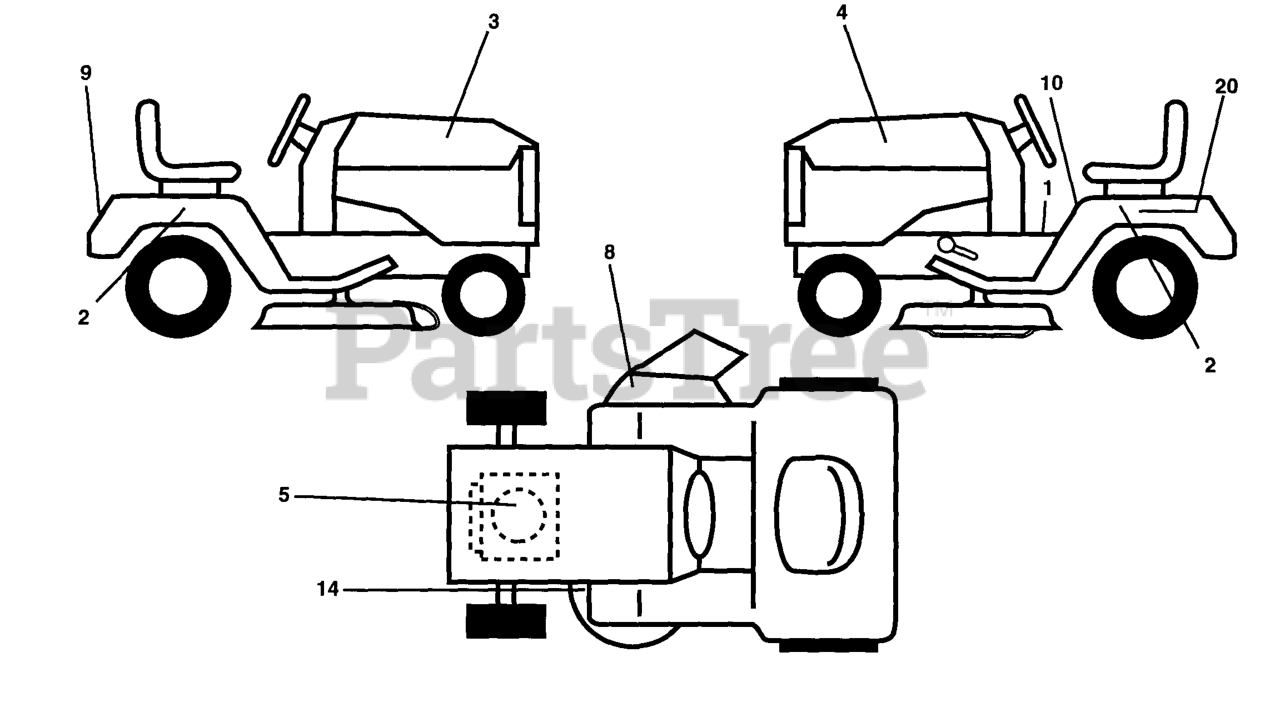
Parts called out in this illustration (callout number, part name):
3	DECAL HOOD LH
4	DECAL HOOD RH
5	DECAL HP ENGINE
8	DECAL WARNING (ENGLISH/FRENCH)
9	DECAL FENDER HUSQ
10	DECAL FENDER DANGER
14	DECAL V-BELT SCHEMATIC
20	DECAL, BATTERY DANGER
